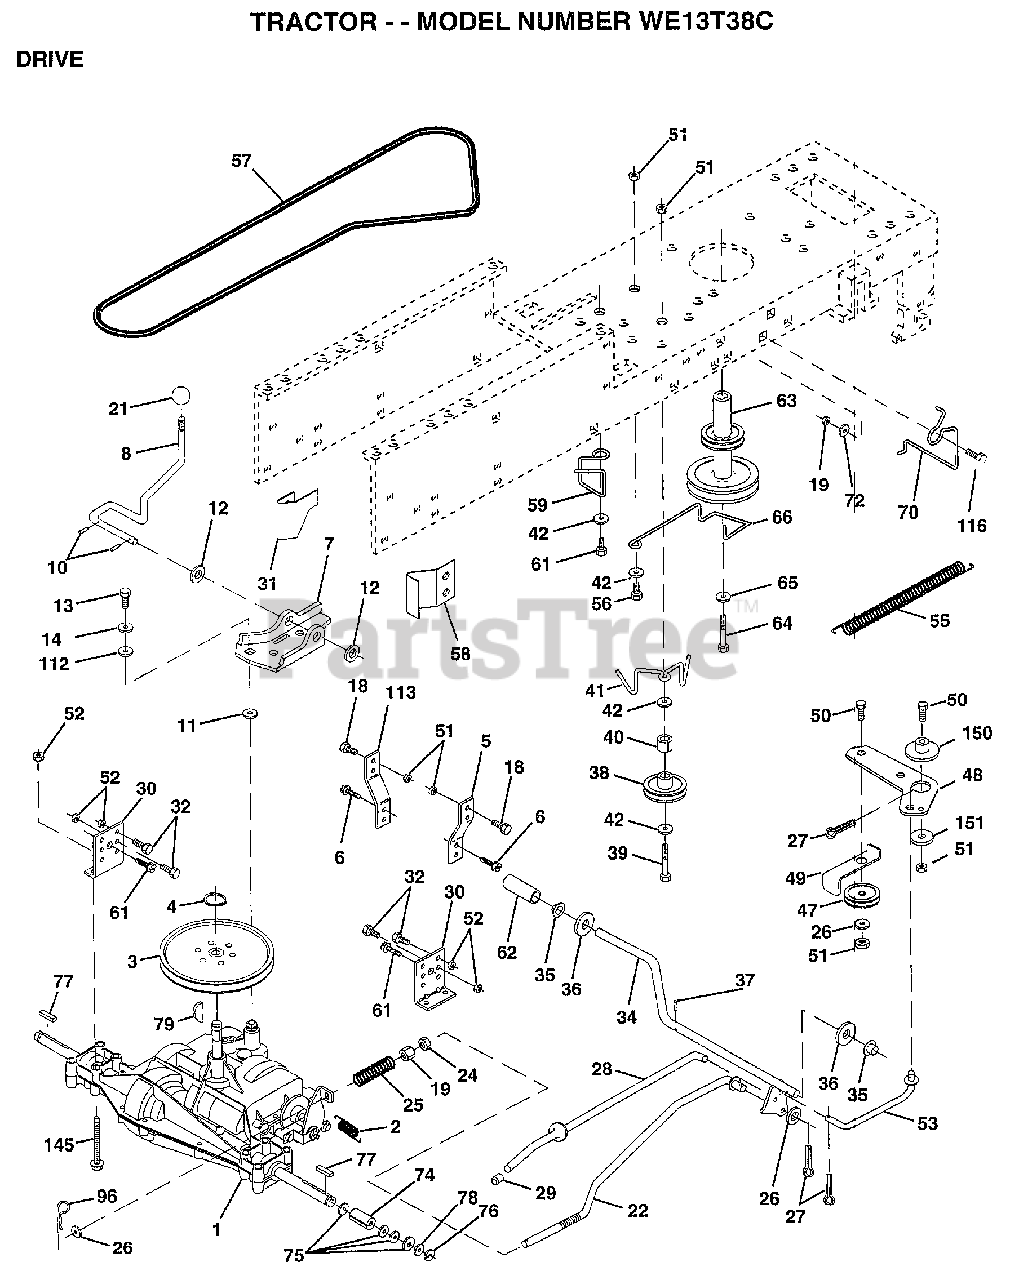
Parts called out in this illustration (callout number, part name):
2	SPRING.BRAKE.RETU
3	PULLEY TRANS
5	STRAP TORQUE
6	SCREW
7	BRKT.SADDLE.SHIFT
8	SHIFT ROD
10	PIN COTTER 1/8
11	WASH-SHFT PLT LT
12	WASHER
13	BOLT.1/4-28.W/PAT
14	LOCKWASHER
15	BOLT.HX.FLG.5/16
18	BOLT
19	NUT
21	KNOB T (1/2-HOLE)
22	BRAKE ROD
24	NUT
25	SPRING ROD LT
26	WASHER
27	COTTER PIN
28	ROD.BRAKE.PARK.LT
29	PLUNGER CAP T
30	TRANSAXLE MTG BKT
31	"KEEPER,BELT LH T"
32	BOLT
34	SHAFT ASM-PEDAL F
35	NYLON BEARING
36	WASHER LT
38	FLAT IDLER PULLEY
39	BOLT
40	SPACER T
41	"KEEPER,BELT.IDLER FLAT"
42	WASHER
48	BELLCRANK.CLUTCH
49	RETAIN BELT
53	"LINK, CLUTCH T"
55	"SPRING, RETURN LT"
58	"KEEPER,BELT RH T"
59	KEEPER BELT CNTSP
61	SCREW
62	PEDAL COVER T
63	PULLEY.ENGINE
64	BOLT
65	LOCKWASHER
66	KEEPER-BELT
70	KEEPER BELT ENG
72	WASHER
74	SPACER AXLE
75	WASHER
76	E-RING LT
77	SQUARE KEY
78	WASHER
96	RETAINER M
112	WASHER LT
113	"STRAP,TORQUE"
116	BOLT RDHD 3/8-16
145	BOLT.HEX.FLGHD
150	BUSHING.BELLCRANK.GRD.DR
151	WASHER
